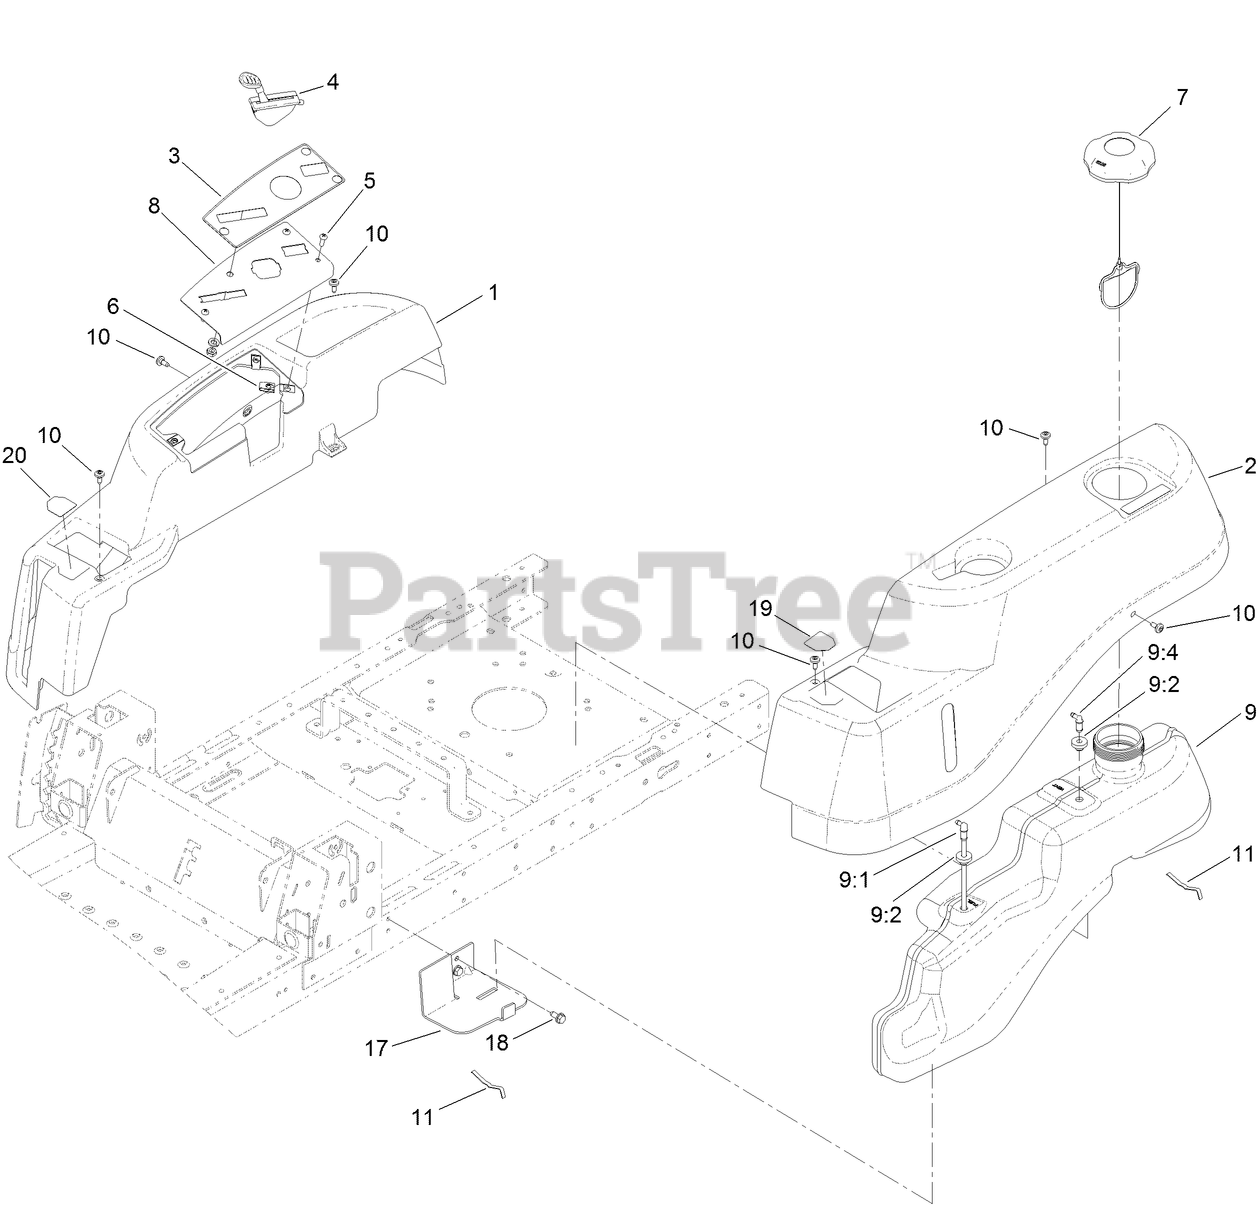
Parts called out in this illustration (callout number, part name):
1	POD-RH
2	POD-LH
3	DECAL-PANEL, CONTROL
4	CABLE-THROTTLE
5	SCREW-PRH
8	PLATE-CONTROL
9	FUEL TANK ASM
9:1	CONNECTOR-ELBOW, 90 DEG
9:2	BUSHING
9:4	FITTING-PLASTIC
10	SCREW-SHOULDER
11	SPRING
17	SUPPORT-TANK, FRONT
18	SCREW-HWHTF
19	DECAL-LEVER, CONTROL (LH)
20	DECAL-LEVER, CONTROL (RH)
